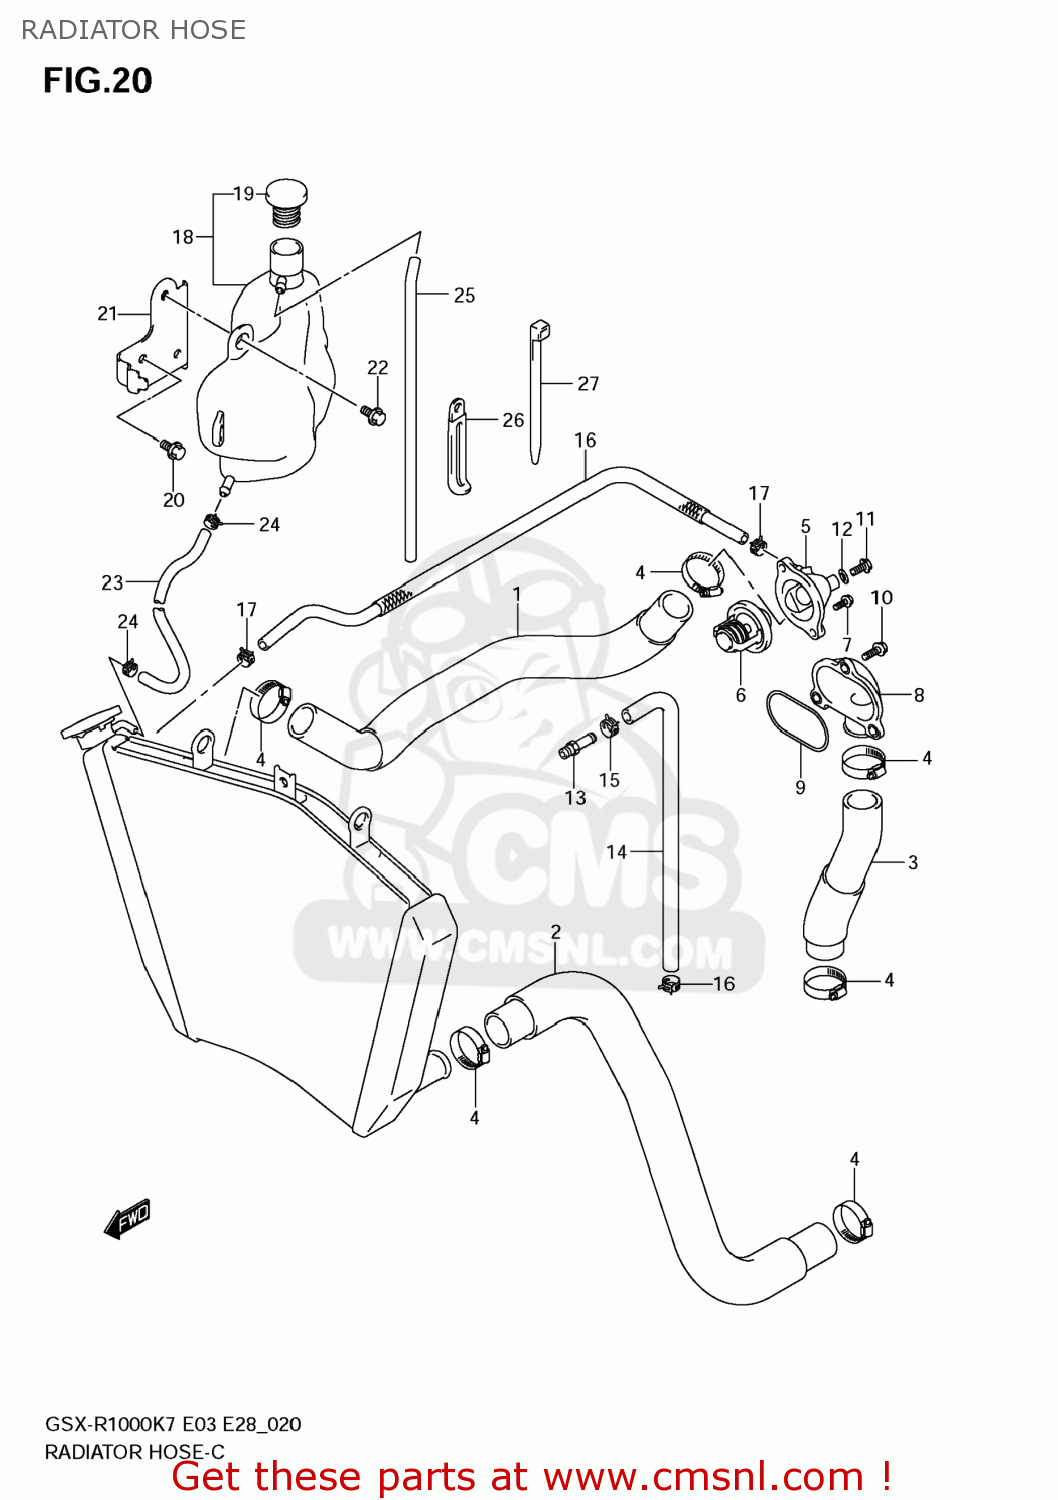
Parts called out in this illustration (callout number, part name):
1	HOSE,RADIATOR INLET
2	HOSE,RADIATOR OUTLET
3	HOSE,CYLINDER INLET
4	CLAMP
5	COVER,THERMOSTAT
6	THERMOSTAT,WATER
7	BOLT
8	CONNECTOR,CYLINDER WATER INLET
9	O RING,CYL WATER CONNECTOR
10	BOLT
11	UNION BOLT,AIR VENT
12	GASKET(6.4X11.5X0.8) (NAS)
13	BOLT UNION
14	HOSE,WATER BYPASS
15	CLAMP
16	HOSE,WATER AIR BLEED
17	CLIP
18	TANK ASSY,RESERVOIR
19	CAP,RESERVOIR TANK
20	BOLT(6X12)
21	BRACKET,RESERVOIR TANK
22	BOLT
23	HOSE,RESERVOIR TANK INLET
24	CLIP
25	HOSE(5X9X2000)
26	CLAMP(L:45)
27	CLAMP(L:95)
